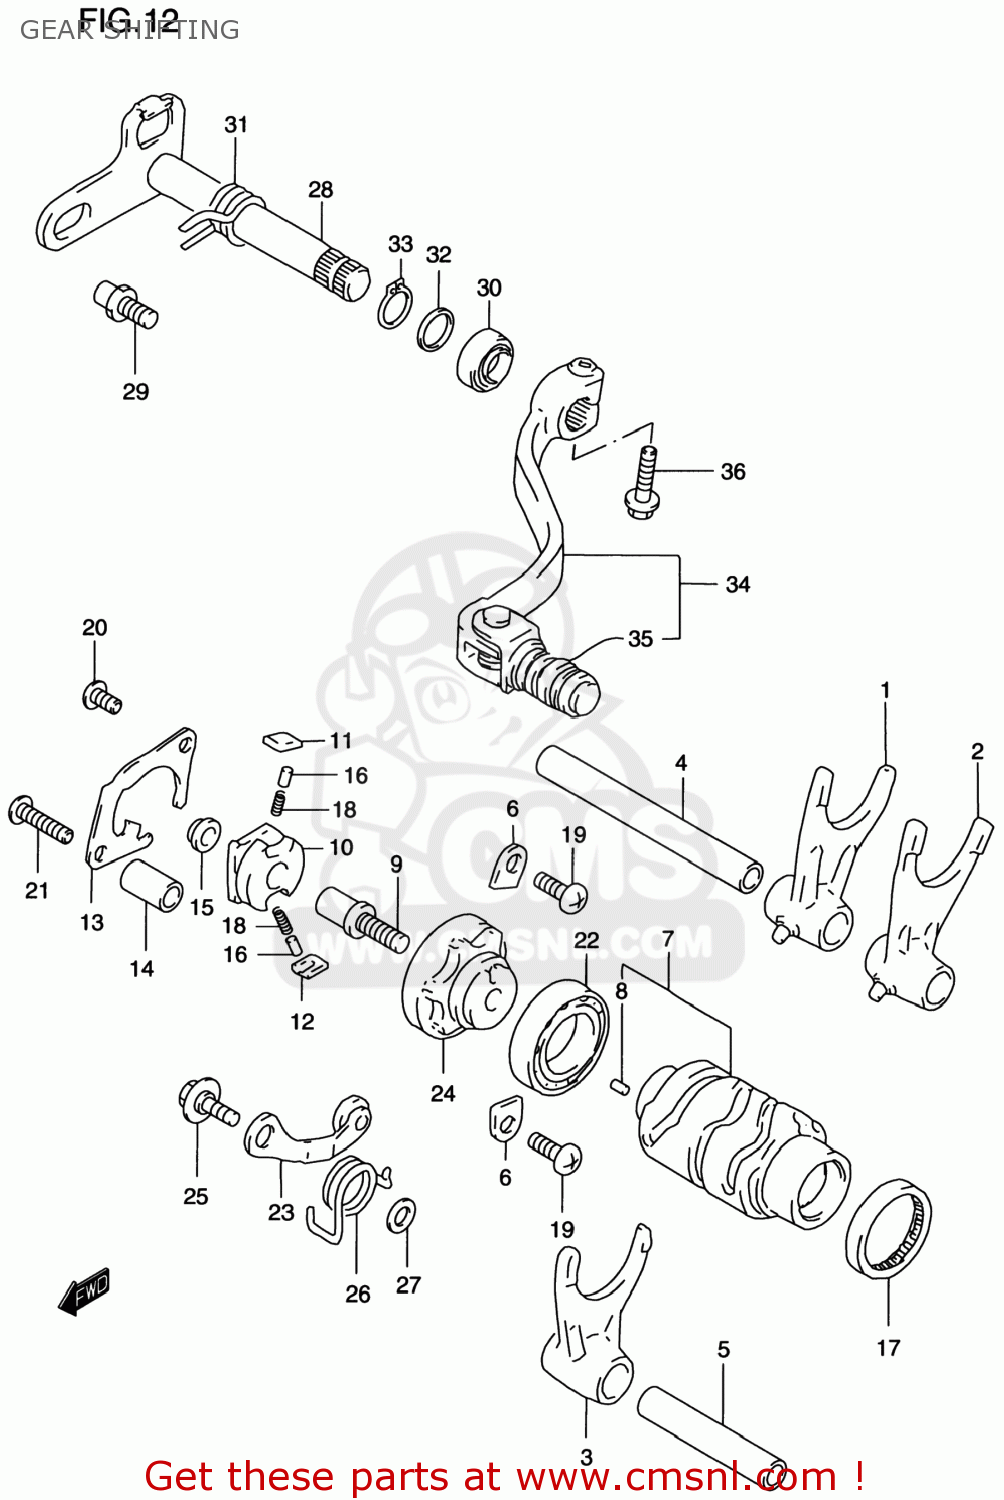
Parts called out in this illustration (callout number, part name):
1	FORK,GEAR SHIFT NO.1
2	FORK,GEAR SHIFT NO.2
3	FORK,GEAR SHIFT NO.3
4	SHAFT,GEAR SHIFT FORK
5	SHAFT,GEAR SHIFT FORK
6	RETAINER
7	CAM,GEAR SHIFT
8	PIN
9	PIN,SHIFT CAM DRIVEN GEAR
10	SHIFTER,GEAR SHIFT CAM
11	PAWL,GEAR SHIFT NO.1
12	PAWL,GEAR SHIFT NO.2
13	LIFTER,GEAR SHIFT PAWL
14	SPACER(6.2X12X18)
15	SPACER(7X10X5)
16	PIN(5X8)
17	BEARING(33X38X8)
18	SPRING
19	SCREW
20	SCREW
21	SCREW
22	BEARING
23	STOPPER,SHIFT CAM
24	PLATE,SHIFT CAM STOPPER
25	BOLT(6X14.3)
26	SPRING
27	WASHER
28	SHAFT,GEAR SHIFT
29	STOPPER,SHIFT ARM
30	SEAL,OIL(14X22X6)
31	SPRING
32	WASHER
33	CIRCLIP
34	LEVER ASSEMBLY,GEAR SHIFTING
35	RUBBER,GEAR SHIFT PEDAL
36	SCREW
